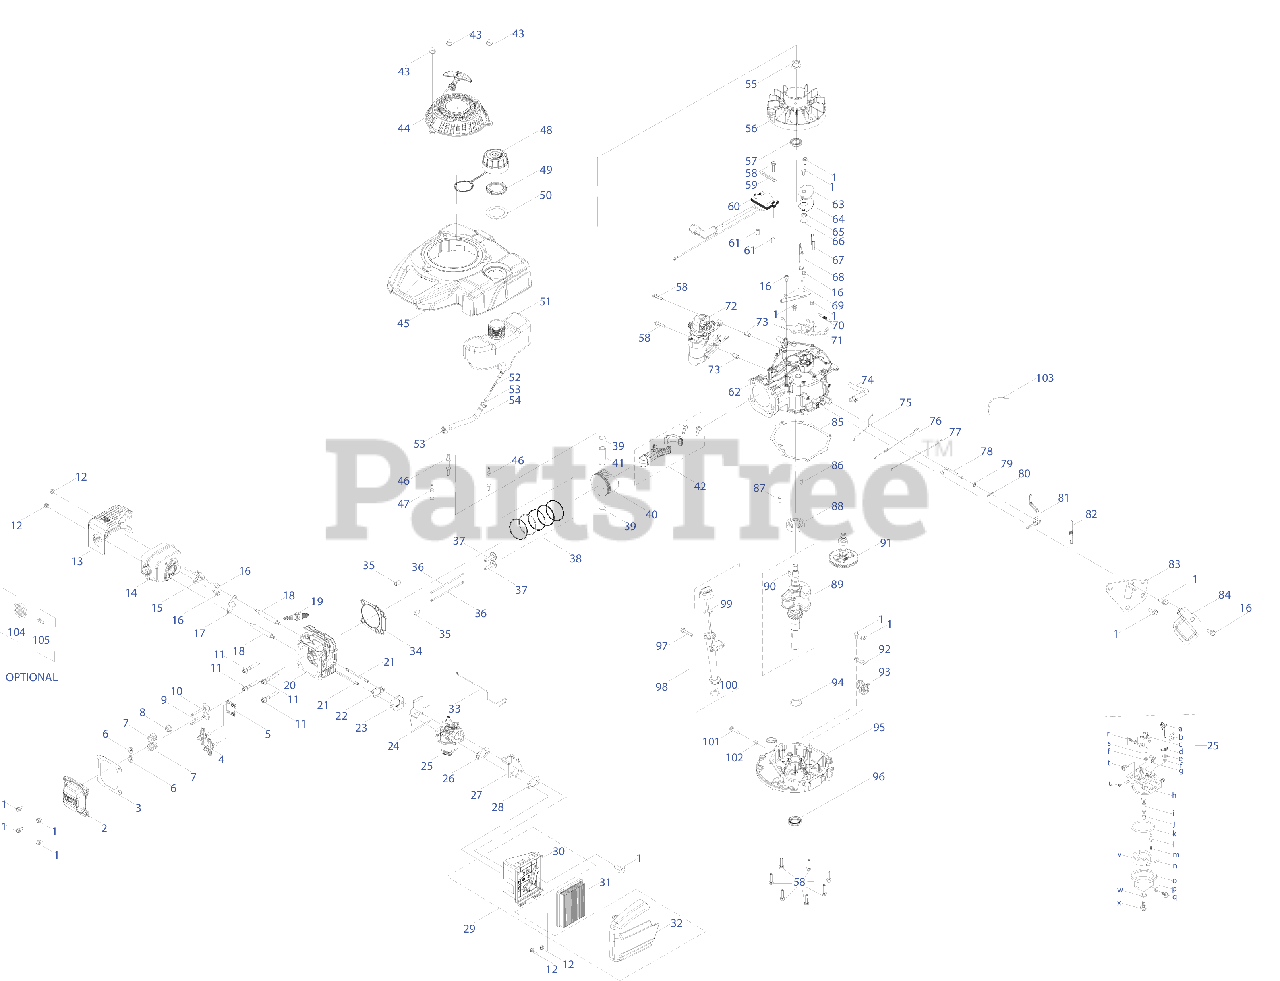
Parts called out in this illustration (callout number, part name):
1	BOLT M6-1 x 14 GR8.8
2	VALVE COVER
3	VALVE COVER GASKET
4	ROCKER ARM ASSEMBLY
5	PUSH ROD GUIDE
6	INTAKE VALVE SPRING RETAINER
7	VALVE SPRING
8	INTAKE VALVE SEAL
9	EXHAUST VALVE
10	INTAKE VALVE
11	SCREW M8 x 54 GR10
12	HEX NUT
13	MUFFLER SHIELD
14	MUFFLER ASSEMBLY
15	THERMOSTAT
16	BOLT M6-1 x 12 GR8.8
17	MUFFLER GASKET
18	STUD M6-1 x 95
19	SPARK PLUG
20	CYLINDER HEAD
21	CARBURETOR STUD-M6 x 87
22	CARBURETOR INSULATOR GASKET
23	CARBURETOR INSULATOR
24	CARBURETOR GASKET
25	CARBURETOR ASSEMBLY HY-5X70A
26	CHOKE TEMP CONTROL BRACKET GSKT
27	AIR FILTER BRACKET
28	AIR FILTER BASE GASKET
29	AIR FILTER ASSEMBLY
30	AIR FILTER HOUSING BASE
31	AIR FILTER
31	Cub Cadet AIR FILTER
31	Genuine Factory Parts AIR FILTER
32	AIR FILTER COVER
33	TEMPERATURE CONTROL LINKAGE
34	CYLINDER HEAD GASKET
35	DOWEL PIN
36	PUSH ROD
37	TAPPET
38	PISTON RING 4PC SET
39	PISTON PIN SNAP RING
40	PISTON ASSEMBLY
41	PISTON PIN
42	CONNECTING ROD ASSEMBLY
43	ACORN NUT
44	RECOIL STARTER ASSEMBLY
45	ENGINE SHROUD W/O IGNITION SWITCH
46	STARTER/SHROUD REAR STUD
47	STARTER SHROUD FRONT STUD M6X74
48	FUEL CAP W/TETHER
49	FUEL TANK NUT
50	FUEL TANK UPPER GROMMET
51	FUEL TANK
52	FUEL FILTER
52	Genuine Factory Parts FUEL FILTER
53	HOSE CLAMP
54	FUEL HOSE
55	FLYWHEEL NUT
56	FLYWHEEL ASSEMBLY
57	CRANKSHAFT SEAL
58	BOLT-M6-1 x 28 GR8.8
59	FLEXIBLE CLAMP
60	IGNITION COIL ASSEMBLY
61	IGNITION COIL SPACER
62	CRANKCASE
63	BREATHER COVER PLATE
64	BREATHER GASKET
65	BREATHER VALVE SPRING
66	BREATHER VALVE
67	BREATHER SCREEN
68	AIR VANE
69	AIR VANE BRACKET
70	ENGINE BRAKE SPRING
71	ENGINE BRAKE ASSEMBLY
72	ELECTRIC STARTER ASSEMBLY
73	DOWEL PIN
74	BREATHER HOSE ASSEMBLY
75	CHOKE LINKAGE
76	THROTTLE SPRING
77	THROTTLE LINKAGE
78	GOVERNOR ARM SHAFT
79	GOVERNOR SEAL
80	COTTER PIN
81	GOVERNOR ARM ASSEMBLY
82	GOVERNOR SPRING
83	COMPONENT BRACKET
84	GOVERNOR SHIELD
85	CRANKCASE COVER GASKET
86	DOWEL PIN
87	DOWEL PIN
88	BEARING
89	CRANKSHAFT ASSEMBLY
90	FLYWHEEL KEY
91	CAMSHAFT ASSEMBLY
92	GOVERNOR GEAR MOUNTING PLATE
93	GOVERNOR GEAR/SHAFT ASSEMBLY
94	THRUST WASHER
95	CRANKCASE COVER
96	LOWER CRANKSHAFT OIL SEAL
97	BOLT M6-1 x 35 GR8.8
98	OIL DIPSTICK ASSEMBLY
99	O-RING
100	O-RING
101	OIL DRAIN PLUG
102	WASHER
103	CABLE TIE - 3 x 150
104	SPARK ARRESTOR
105	SCREW M3.5 x 9.5
